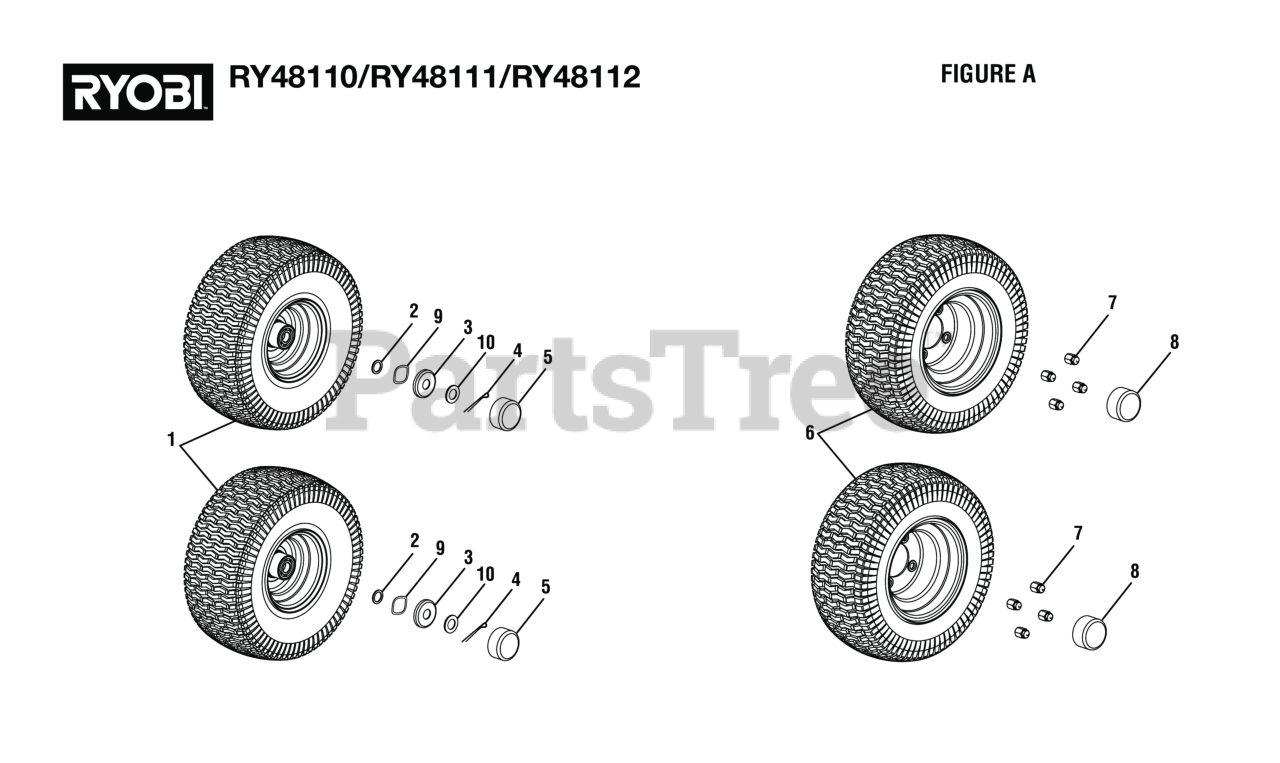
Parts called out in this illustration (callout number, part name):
1	Front Wheel Assembly
2	Washer (OD28 x ID20.5 x 2t)
3	Front Wheel Bearing Cover
4	Cotter Pin (4 x 40 mm)
5	Dust Cover, Front Wheel
6	Rear Wheel Assembly
7	Acorn Nut (M14)
8	Wheel Hub Cover
9	Wavy Washer
10	Washer (OD37 x ID21 x 0.3t)
